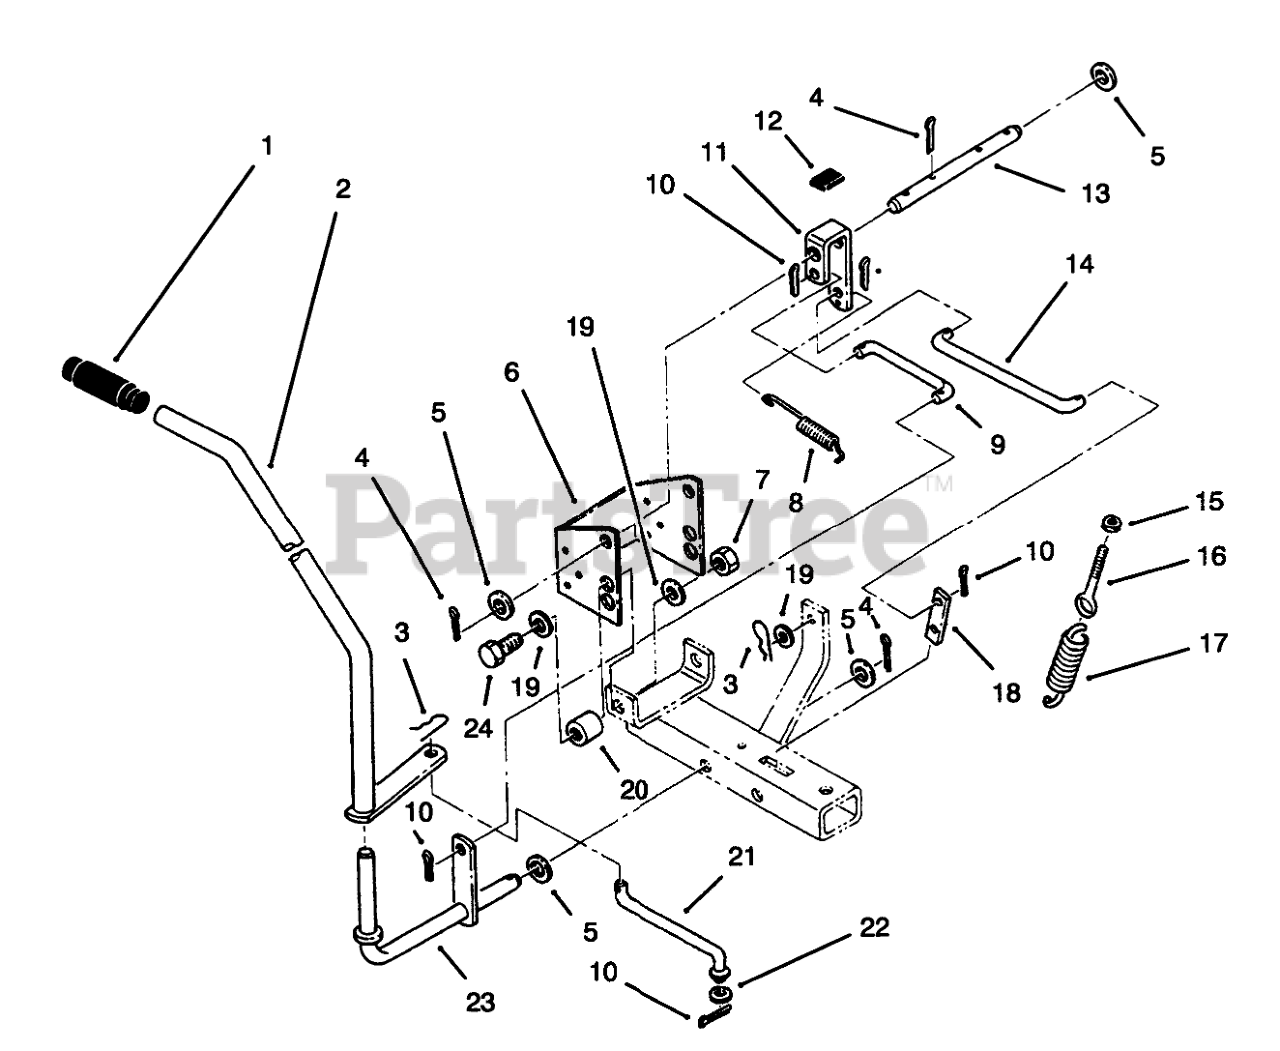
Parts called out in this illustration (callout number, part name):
1	HANDGRIP
2	Handle
3	Hairpin
4	PIN-COTTER
5	WASHER-FLAT
6	BRACKET MOUNT
7	NUT-LOCK, NI
8	SPRING
9	ROD-BELLCRANK
10	PIN-COTTER
11	Bellcrank
12	RUBBER PAD
13	SHAFT
14	ROD-LATCH
15	NUT-JAM
16	EYEBOLT
17	SPRING
18	Latch
19	WASHER-FLAT
20	SPACER
21	ROD-ANGLING
22	WASHER-FLAT
23	Pivot-Handle
24	SCREW-HH
